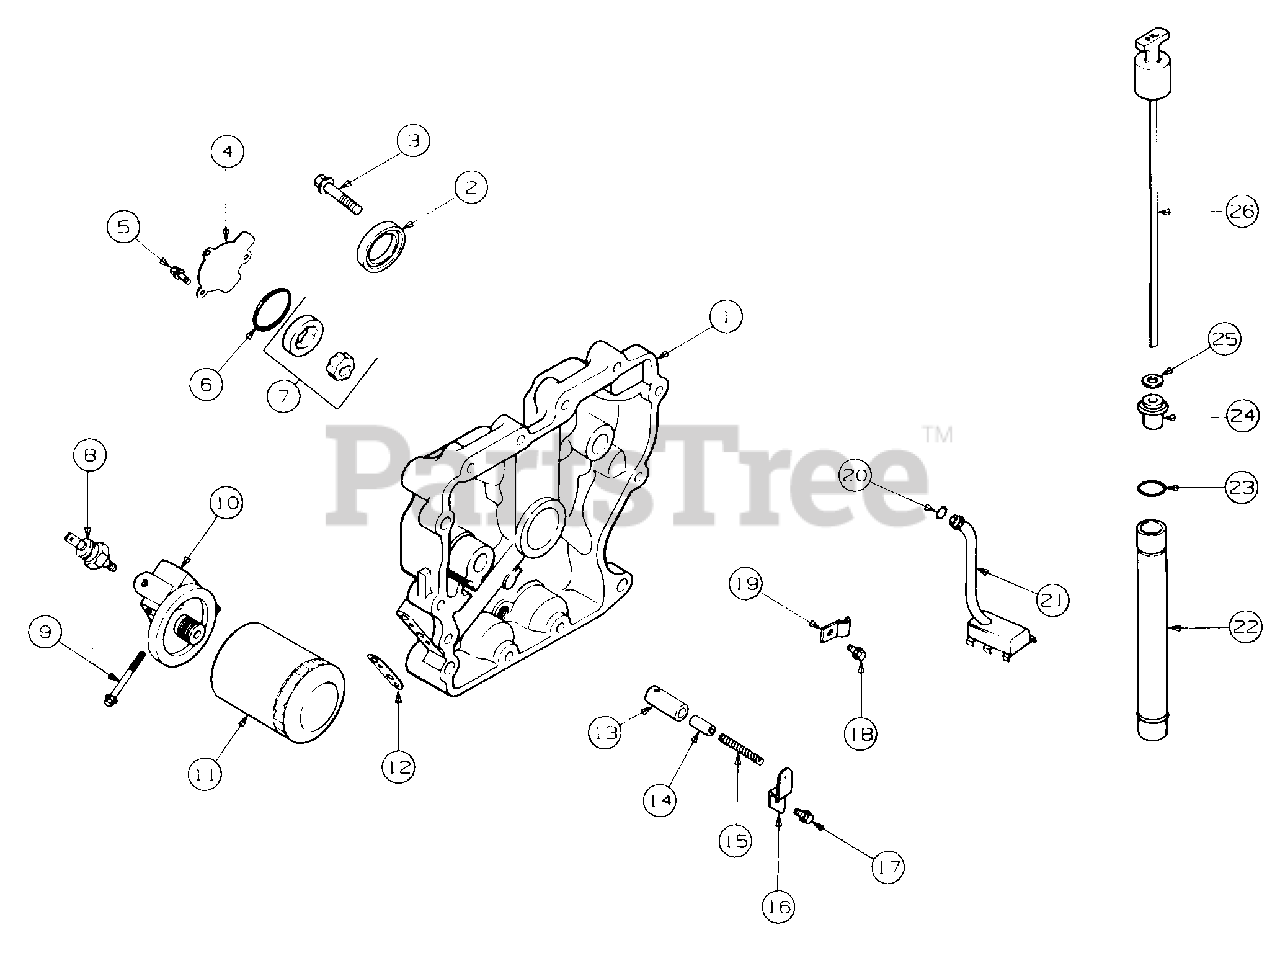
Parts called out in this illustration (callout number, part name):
1	Plate, Closure
2	Seal, Oil (PTO end)
3	Screw, Closure Plate M8 x 1.25 x 45
4	Cover, Oil Pump
5	Screw, Oil Pump Cover, M5 x 0.8 x 16
6	O-Ring, Oil Pump
8	Switch, Oil Pressure
9	Screw, Oil Filter Adapter, M6 x 1.0 x 55
10	Adapter, Oil Filter
11	Filter, Oil
12	Gasket, Oil Filter Adapter
13	Body, Oil Pump Relief Valve
14	Piston, Oil Pump Relief Valve
15	Spring, Oil Pump Relief Valve
16	Bracket, Oil Pump Relief Valve
17	Screw, Screen Cover M5 x 0.8 x 16
18	Screw, Oil Pick-Up M5 x 0.8 x 16
19	Clip, Oil Tube
20	O-Ring, Oil Pick-Up
21	Oil Pick-Up Assy
22	Tube, Oil Fill
23	O-Ring, Lower Oil Fill Tube
24	Seal, Rubber
25	Washer, Plain, 5/16
26	Dipstick Assy
